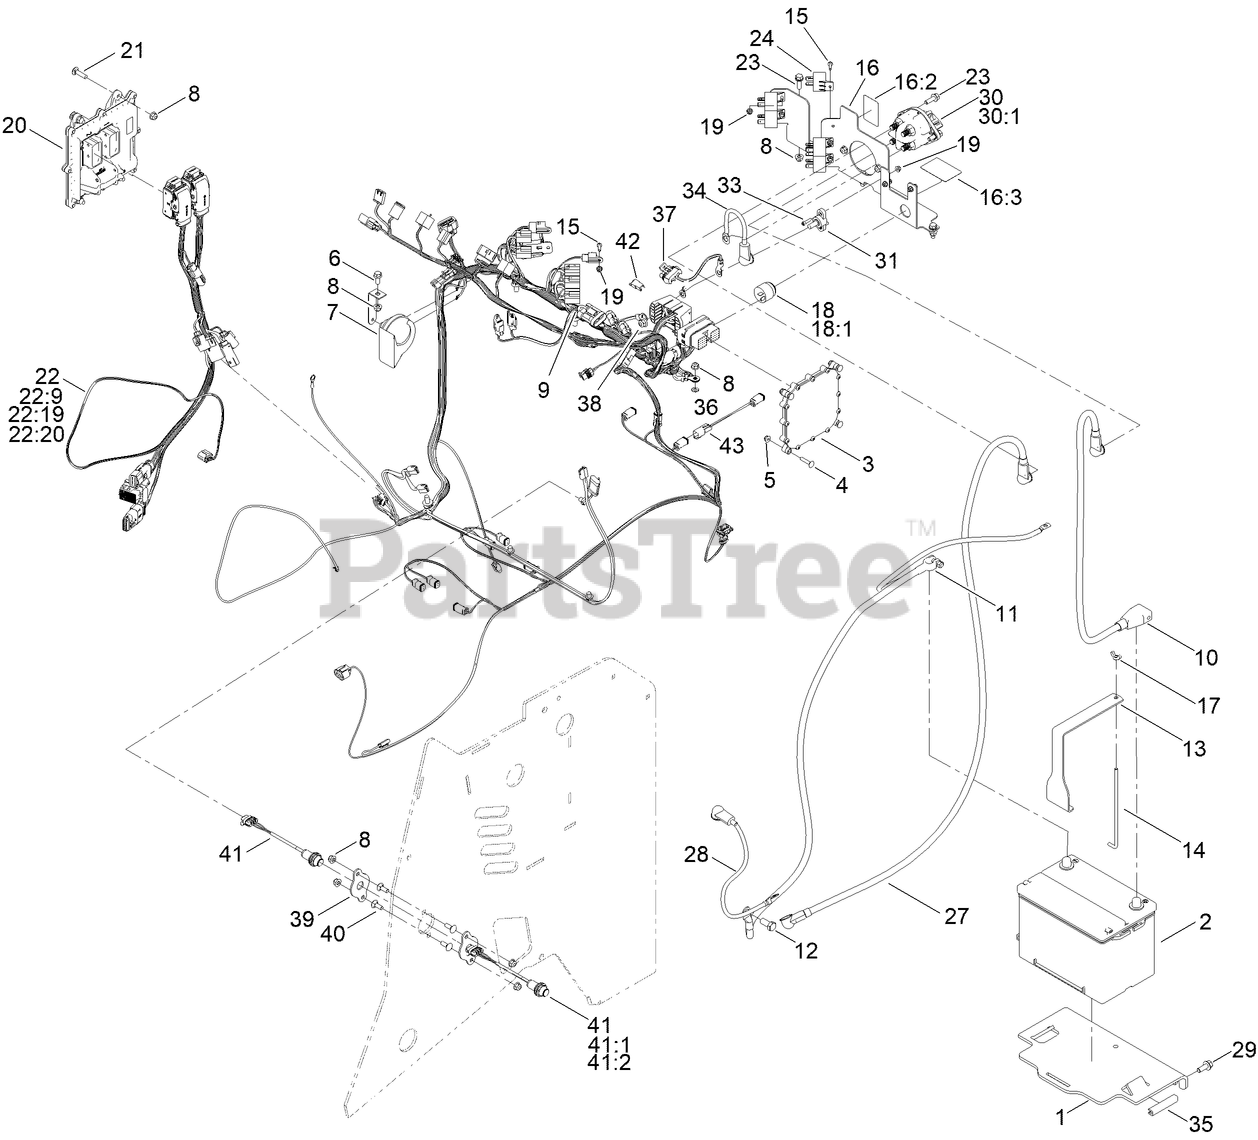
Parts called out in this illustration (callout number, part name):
1	BRACKET-BATTERY
2	BATTERY
3	CONTROLLER
4	SCREW-CARR
5	NUT-HF
6	SCREW-HHF
7	Horn And Bracket Assembly (Inc. Ref.# 44 45)
8	NUT-HF, NI
9	HARNESS-WIRE
10	CABLE-BATTERY, POSITIVE
11	CABLE-BATTERY, NEGATIVE
12	SCREW-HH
13	PLATE-HOLD, BATTERY
14	ROD-HOLD DOWN, BATTERY
15	SCREW-HWH
16	BRACKET-COMPONENTS, ELECTRICAL
16:2	DECAL-BATTERY POWER
16:3	DECAL-FUSES
17	NUT-WING
18	AUDIO ALARM ASM
18:1	NUT-PLASTIC, KNURLED
19	NUT-HF
20	ECU-ENGINE
21	SCREW-CARR
22	HARNESS-ENGINE
23	SCREW-HHF
24	RELAY
27	CABLE-BATTERY, POSITIVE
28	CABLE-BATTERY, POSITIVE
29	SCREW-HHF
30	SWITCH-DISCONNECT
30:1	NUT-HF
31	BLOCK-JUNCTION
33	SCREW-HSH
34	CABLE-BATTERY, POSITIVE
36	WASHER-LOCK
37	HARNESS-WIRE, FUSIBLE LINK
38	NUT-HF, NI
39	PLATE-MOUNT, SENSOR
40	SCREW-CARR
41	PROXIMITY SWITCH ASM
41:1	NUT-HEX
41:2	WASHER-LOCK, INTERNAL TOOTH
42	HARNESS-WIRE, FUSIBLE LINK
43	HARNESS-JUMPER
